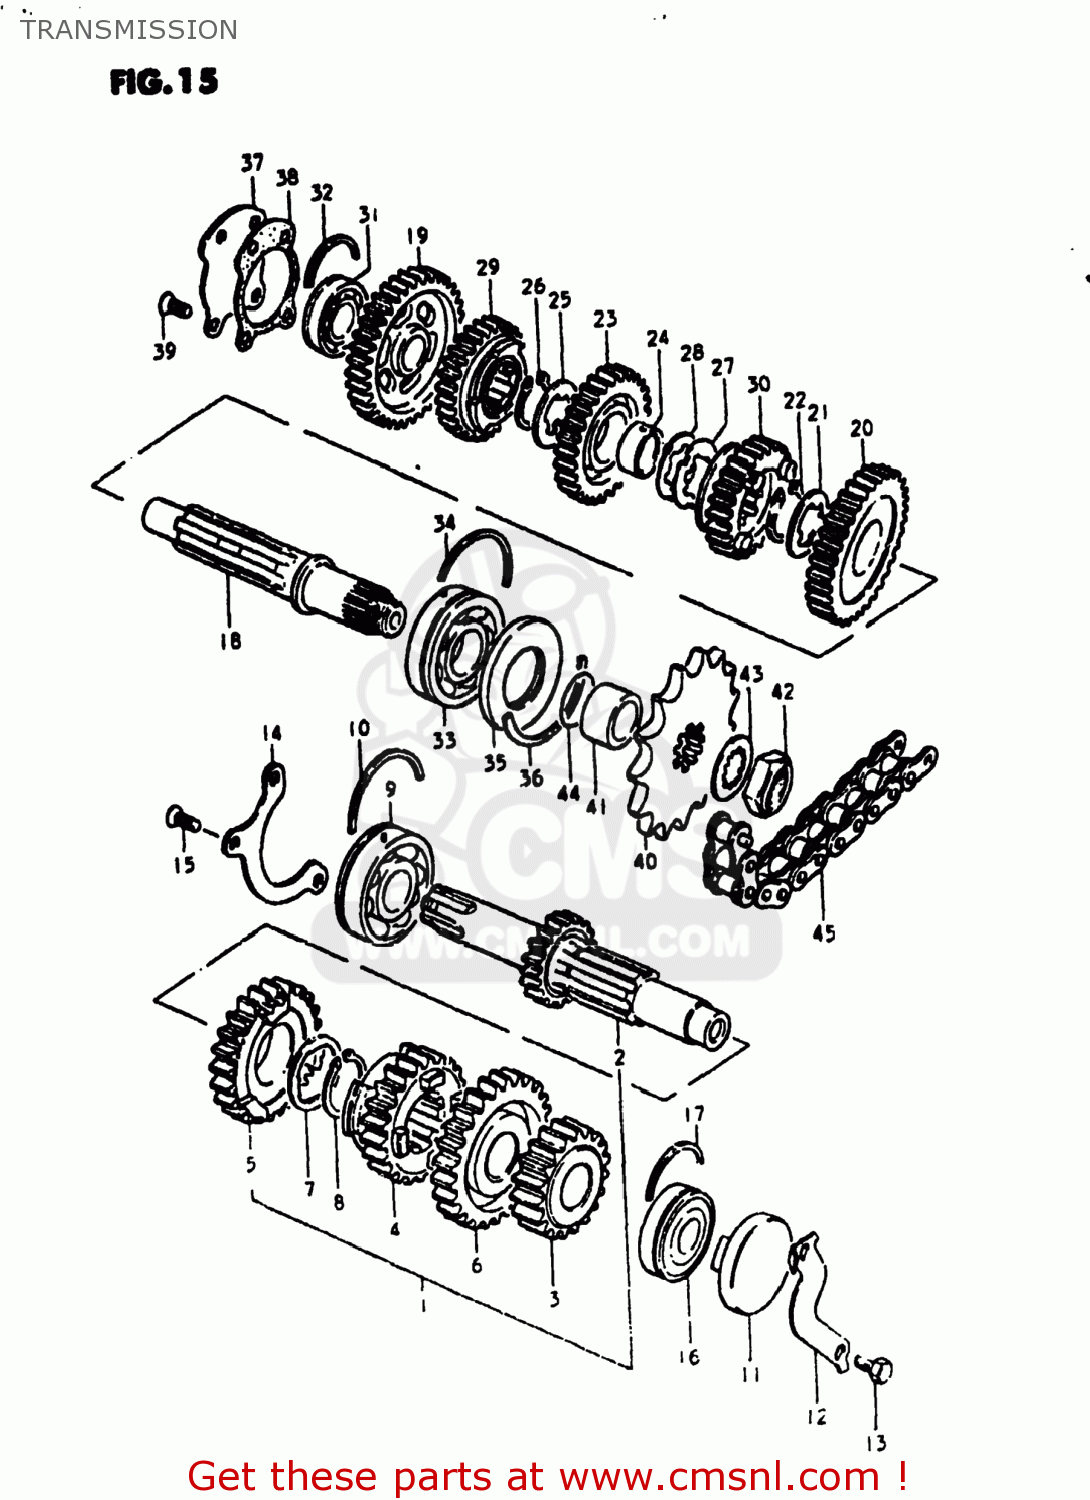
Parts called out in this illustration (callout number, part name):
1	SHAFT ASSEMBLY,COUNTER
2	SHAFT,COUNTER
3	GEAR,SECOND DRIVE
4	GEAR,THIRD DRIVE
5	GEAR,FOURTH DRIVE
6	GEAR,FIFTH DRIVE
7	WASHER,LOCK
8	CIRCLIP
9	BEARING(25X62X17)
10	C-RING
11	PLUG
12	RETAINER,CL PUSH ROD OIL SEAL
13	BOLT
14	RETAINER,CNTR SHAFT BEARING
15	SCREW
16	BEARING(20X47X14)
17	C RING
18	SHAFT,DRIVE
19	GEAR,FIRST DRIVEN
20	GEAR,SECOND DRIVEN
21	WASHER,LOCK
22	CIRCLIP
23	GEAR,THIRD DRIVEN
24	BUSH,3RD DRIVEN GEAR
25	WASHER,LOCK
26	CIRCLIP
27	WASHER,LOCK
28	WASHER
29	GEAR,FOURTH DRIVEN
30	GEAR,FIFTH DRIVEN
31	BEARING
32	C RING
33	BEARING(25X62X17)
34	C-RING
35	SEAL,OIL(32X62X7)
36	C RING
37	PLATE,DRIVE SHAFT
38	GASKET,DRIVESHAFT PLATE (MCA)
39	SCREW
40	SPROCKET,ENGINE
41	SPACER(25X32X18.6)
42	NUT
43	WASHER
44	O RING(D:1,ID:24.5)
45	CHAIN ASSEMBLY,DRIVE
